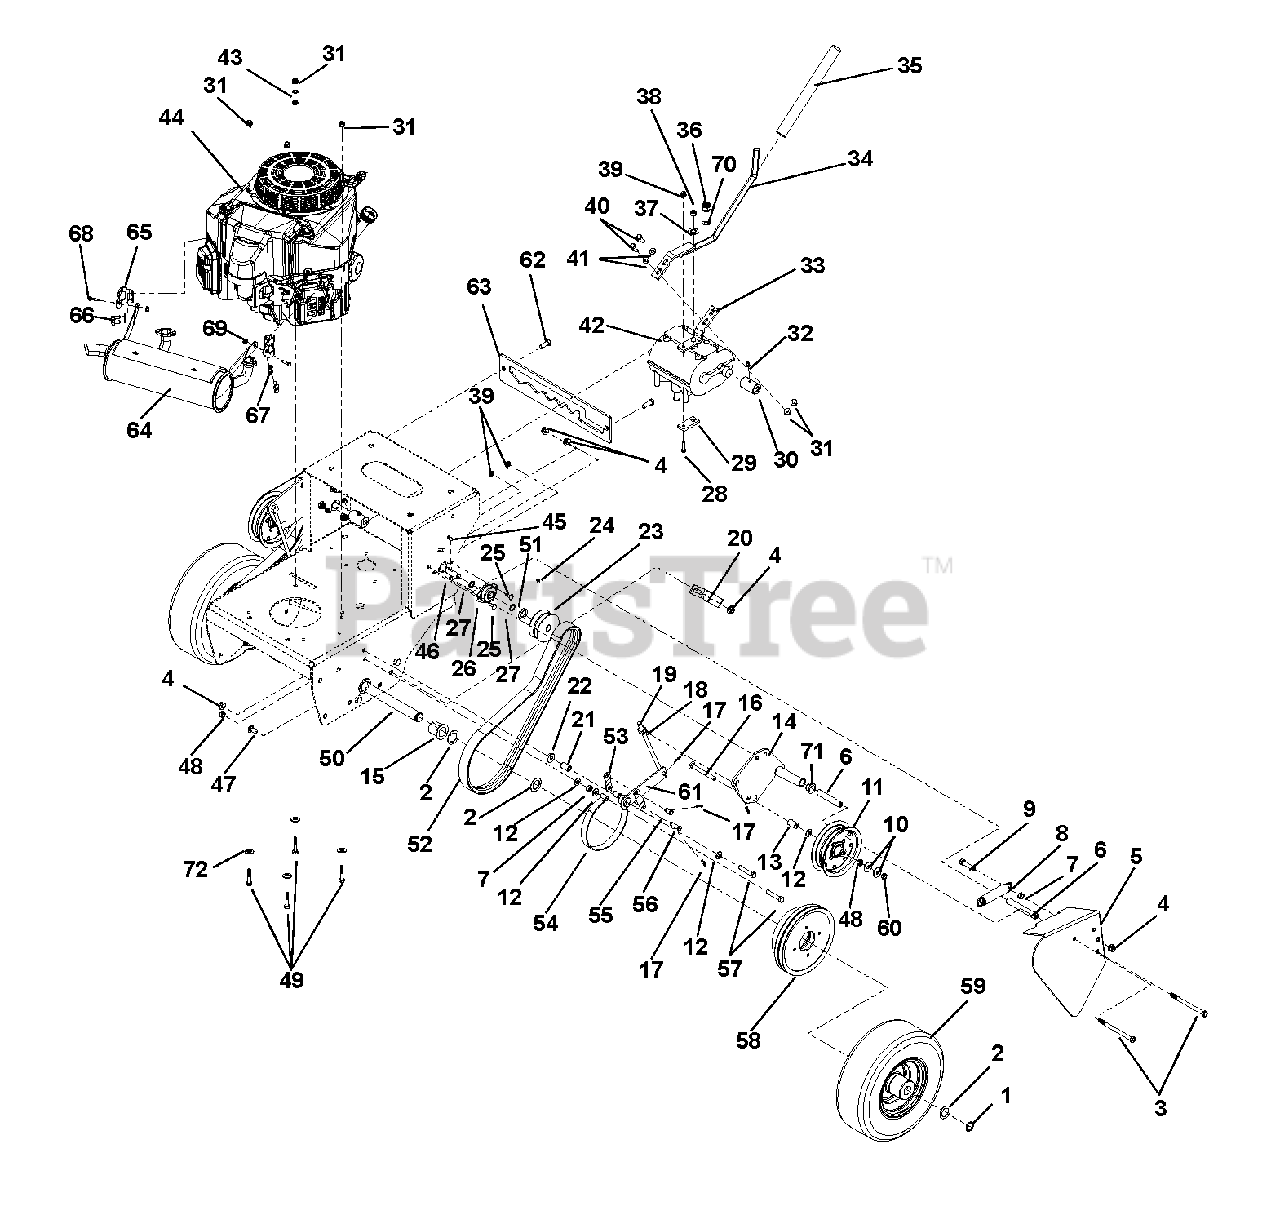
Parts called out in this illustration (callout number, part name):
1	Ring, Retaining-External 1.00 x .078
2	Washer, Flat-Steel 1.010 x 1.505 x .062
3	Bolt, .38-16 x 5.00 Hex Grade 5
4	Nut, Nyloc Flange, .38-16
5	Cover, RH Traction Belt
5	Cover, LH Traction Belt
6	Bushing, S.385 x .610 x 4.32 Steel
7	Nut, Hex .38-16
8	Spring-Tension .105 x 1.00 x 5.0
9	Bolt, .38-16 x 1.75 Hex Grade 5
10	Washer, Flat Steel .375 x 1.125 x .065
11	Pulley, FLat 5.00 x .375 w/Bearing
12	Washer, .406 x .812 x .065 Flat
13	Bushing, Sleeve .375 x .625 x 1.000
14	Weldment, Wheel Clutching Arm
15	Bushing, Flange 1.010 x 1.38 x 1.4 x 1.65
16	Bolt, Round Head Square Neck .38-16 x 3.5 Grade 5
17	Pin, Hair
18	Swivel, .375-24
19	Rod, Brake Actuating
20	Plate, Belt Finger
21	Bushing, S.391 x .622 x .95 St
22	Washer, Flat Steel .406 x 1.00 x .188
23	Sheave, Drive 3.25 x .625 ID
24	Screw, Set .31-18X.38 Socket Head
25	Bolt, .25-20 x .750 Round Head Square Neck Grade 5
26	Bearing, Flange .625 x 1.875 x .797
27	Ring, Retaining-External .579 x .035
28	Bolt, .25-20 x 1.00 Hex Grade 5
29	Plate, Shift
31	Nut, Nyloc Flange, .31-18
32	Fitting, .25-28 STRGT Grease Zerk
33	Bracket, Shift Lever
34	Weldment, Shift Lever
35	Grip, Handlebar
36	Switch, Neutral Start (N.O.)
37	WSHR-LK .375 X .130 YWZC
38	Nut, Locking-Center .375-24
39	Nut, Nyloc Flange, .25-20
40	Bolt, .31-18 x 1.00 Hex Grade 5
41	Washer, Flat Steel .344 x .688 x .065
42	Transmission
43	Washer, Locking-EXT .326 x .599 x .031
44	Engine, Kawasaki (SN 000101 – 010000)
44	Engine, Kawasaki FS481 (SN 010001 +)
45	Key, Woodruff .19 x .75 HRD#9
46	Shaft, Half
47	Bolt .38-16 x 1.00 Round Head Square Neck Grade 5
48	Locknut, .38-16 Center
49	Bolt, Hex .38-16 x 1.25 FTH Grade 5 EP80YZ (SN 000101 – 020999)
49	Bolt, Hex .38-16 x 1.25 Grade 5 NYTORQ (SN 021000 +)
50	Shaft, Axle
51	Washer, Flat .765 x 1.125 x .187
52	Belt, Gear Drive 49" Elbow COG
53	Link, Brake Arm
54	Assembly, Brake Band, Pro
55	Pin, Clevis .38 x .750
56	Pin, Clevis .38 x 1.25
57	Bolt, .375-16 x 2.00 Hex Grade 5
58	Assembly, Pulley and Drum
59	Assembly, Wheel and Tire 6 x 3.5 (988150)
59	Assembly, Wheel and Tire 6 x 4.5 (988151, 152)
60	Nut, Locking-Jam-Center .375-16
61	Weldment, Brake Actuating Lever
62	Bolt, Hex .38-16 x 1.00 Grade 5
63	Plate, Shift Lever Detent
64	Muffler, Kawasaki FS PROWALK (SN 021000 +)
65	Bracket, Exhaust (SN 021000 – 029999)
66	Bolt, Hex M8-1.25 x 20 (SN 021000 +)
67	Washer, Locking .31 x .078 Regular (SN 021000 +)
68	Bolt, Hex .25-20 x 1.00 Grade 5 (SN 021000 +)
69	Nut, Locking Nylon Flange .25-20 (SN 021000 +)
70	Washer, Flat .563 x 1.00 x 18GA
71	Bushing, Flange, .625 x .750 x 1.00
72	Washer, 3/8" Spring Disc (SN 021000 +)
73	Air Filter
74	Oil Filter
75	Fuel Filter
76	Spark Plug
